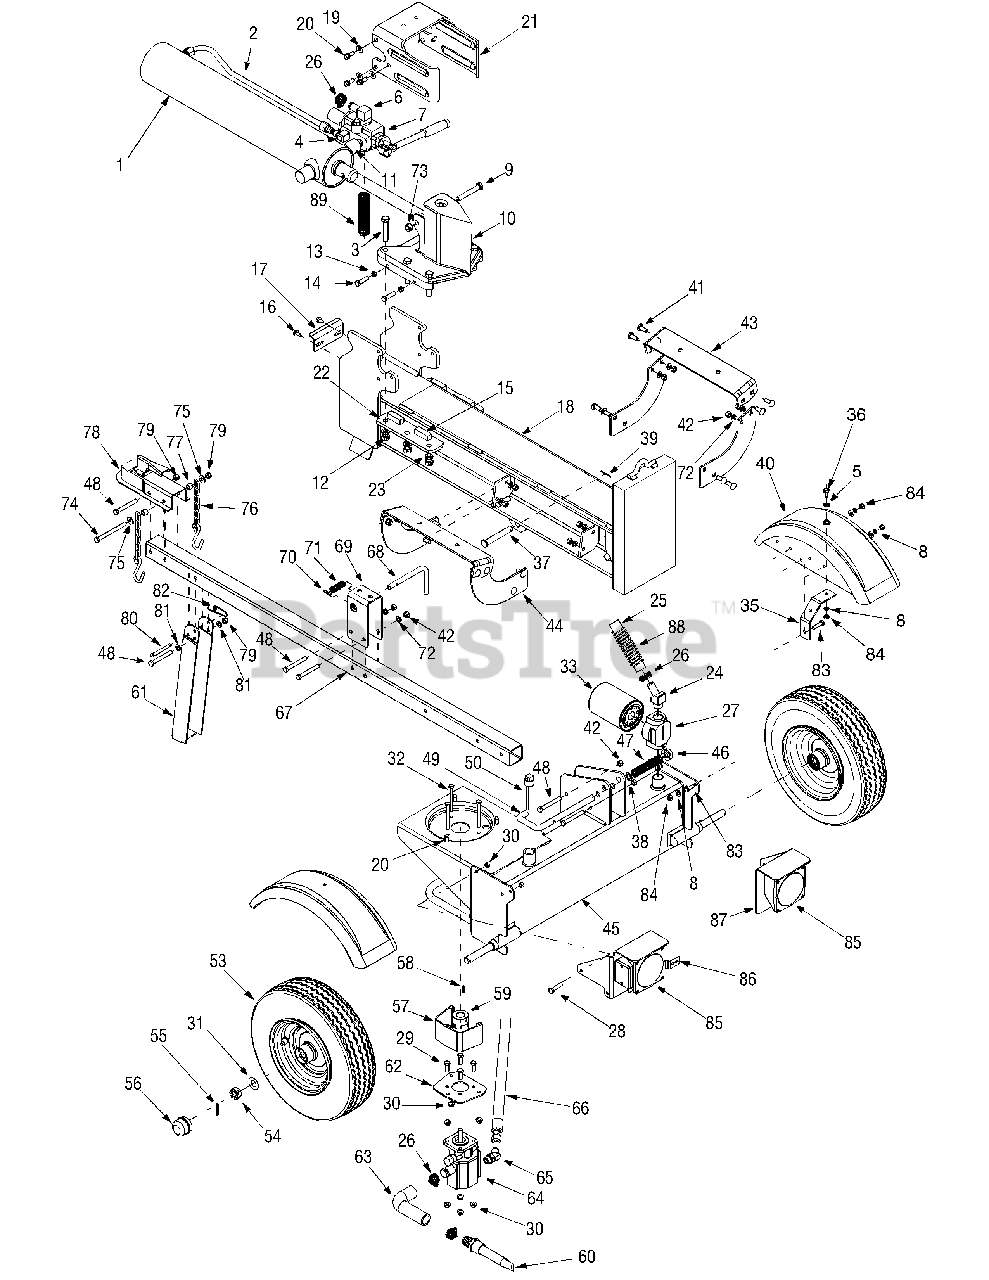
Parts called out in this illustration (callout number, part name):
1	Hydraulic Cylinder 718-0769A
1	Kit Seal 4.5" for XINGHUI cylinder 718-0769A
1	Kit Seal 4.5" for ENERGY cylinder 718-0769A
2	Hydraulic Tube
3	Hex Cap Screw 1/2-20 x 2.75
4	90° Solid Adapter
5	Flat Washer, .434 x .880 x .062
6	Return Elbow
7	Control Valve
8	Lock Washer, 5/16
9	Hex Cap Screw 1/2-13 x 3.25
10	Wedge Assembly
11	Nipple Pipe 1/2-14
12	Lock Nut 1/2-20
13	Hex Jam Nut 3/8-24
14	Hex Cap Screw 3/8-24 x 1.5
15	Adjustable Gib
16	Screw 5/16-18 x.75
17	Cylinder Support Bracket
18	Beam Assembly
19	Flat Washer.406 ID x.875 OD
20	Hex Washer Screw 3/8-16 x 1.0
22	Back Plate
23	Lock Washer 1/2
24	Adapter 3/4-14
25	Return Hose 3/4" ID x 44"
26	Hose Clamp 5/8"
27	Filter Housing
28	Hex Screw, 5/16-18 x 1.25
29	Hex Screw , 5/16-18 x 1.0
30	Hex Flange Nut, Nylon, 5/16-18
31	Flat Washer.760 ID x.500 OD
32	Hex Bolt 5/16-18 x 3.25"
33	Oil Filter
35	Mounting Bracket, Fender
36	Hex Screw, 5/16-18 x .875
38	Flat Washer.635 ID x.93 OD
39	Cotter Pin
40	Fender, Black
41	Carriage Bolt 3/8-16 x 1.0
42	Hex Nut 3/8-16
44	Log Tray Bracket
47	Compression Spring
48	Hex Bolt 3/8-16 x 3.25"
50	Vented Dipstick
51	Hex Screw 5/16-24 x 3.25
53	Wheel Assembly
53	Cone Bearing
53	Grease Retainer
54	Slotted Nut 3/4-16
57	Coupling Shield
58	Square Key 3/16" x.75
59	Flexible Coupling
61	Jack Stand
62	Rear Coupling Support Bracket
65	45 degree Elbow
66	High Pressure Hydraulic Hose
67	Tongue Tube Assembly
68	Tongue Latch Rod
70	Spiral Pin
71	Compression Spring
72	L-Washer 3/8"
73	Hex Lock Nut 1/2-13
74	Hex Cap Screw 3/8-16 x 4.25
75	Flat Washer.385 ID x.870 OD
77	Spacer.375 ID x.625 OD
78	Hitch Coupler
79	Hex Lock Nut 3/8-16
81	Flat Washer.375 ID x.738 OD
83	Hex Screw, 5/16-18 x .875
84	Hex Nut, 5/16-18
86	Light Bracket, LH
87	Light Bracket, RH
